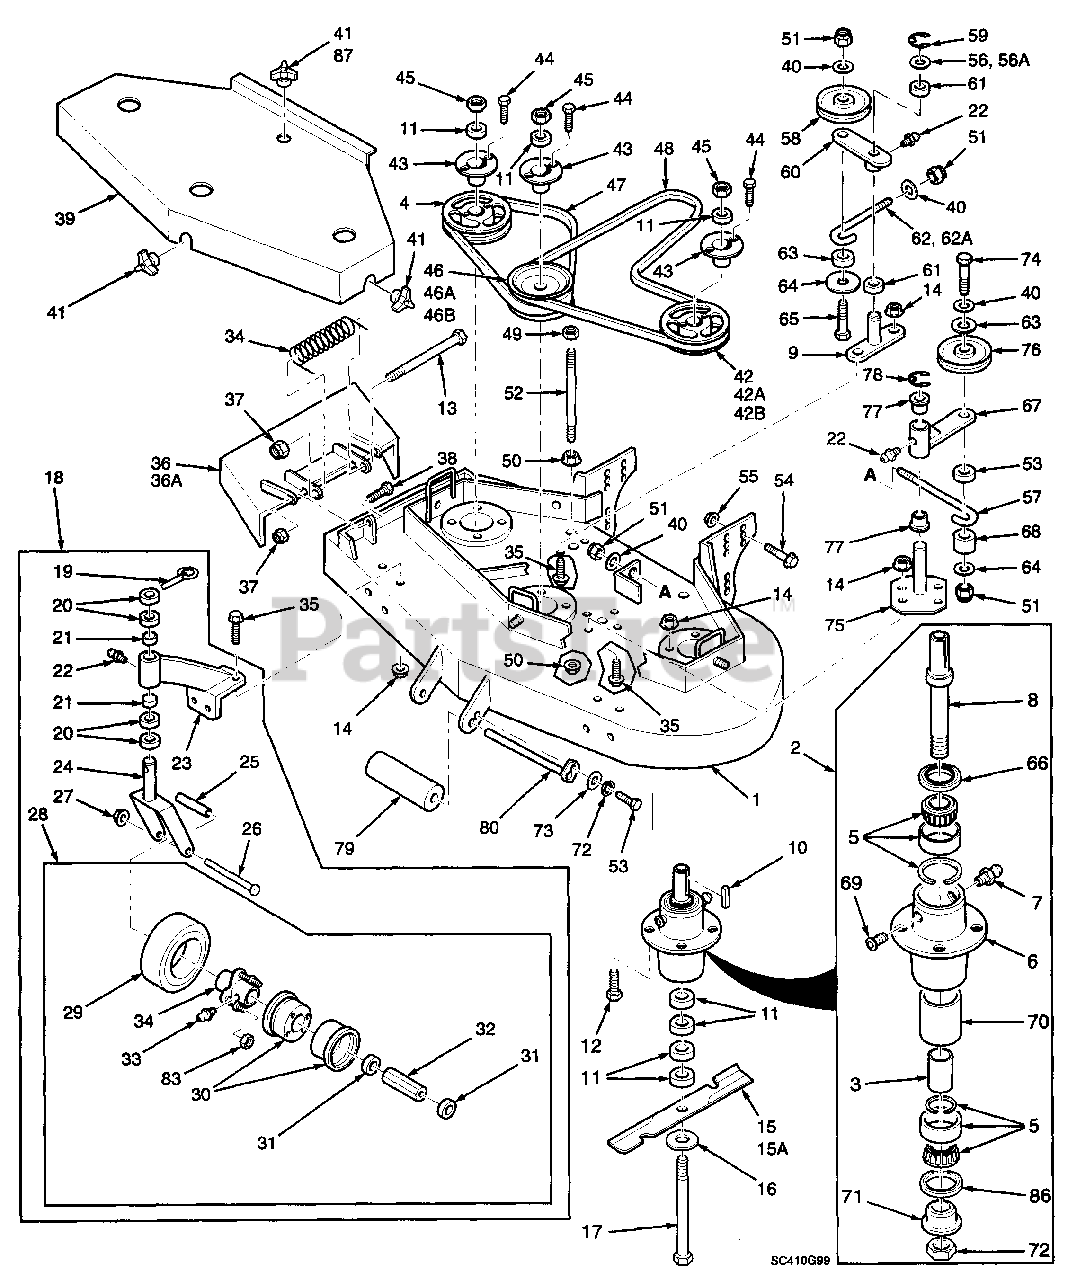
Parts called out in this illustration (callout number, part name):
1	Cutter Deck
2	Spindle Assembly
3	Spacer, Inside
4	Pulley
5	Tapered Bearing (Two)
6	Spindle Housing
7	Grease Fitting Str. 5/16
8	Spindle Shaft, Tapered Brng
9	Idler Pivot
10	Key, 1/4 x 1/4 x 2"
11	Spacer, Cutter Blade - Small
12	Bolt, 5/16-18 x 1-1/4" Hex Head
13	Bolt, 5/16-18 x 4-1/4" Hex Head
14	Serrated Flange Nut, 5/16-18
15	Cutter Blade 16-1/2"
15A	Cutter Blade 16-1/2 Hi Lift
16	Flatwasher, 5/8" (.688 x 1.75 x .134)
17	Hex Head Bolt, 5/8-11 x 9-1/2"
18	Caster Assembly
19	Quick Pin
20	Spacer, Caster Yoke, 1/2" thick
21	Bronze Bearing
22	Lock Wshr, 5/16"
23	Support Assembly
24	Caster Yoke
25	Sleeve, Caster Wheel Bearing
26	Hex Hd Bolt, 1/2-13 x 5-1/2"
27	Elastic Stop Nut, 1/2-13
28	Wheel Assy.
29	Tire only, Caster Wheel
30	Rim Pair, Caster Wheel
31	Bearing Retainer, Caster Wheel
32	Roller Bearing, Caster Wheel
33	Grease Fitting 45 deg., 1/4-28
34	Hub Assembly
35	Capscrew, 5/16-18 x 3/4"
36	Discharge Chute
36A	Discharge Chute
37	Nut, 5/16-18 Elastic Stop
38	Bolt, 5/16-18 x 1" Hex Head
39	Belt Cover
39	Belt Cover 17KA
40	Flat Washer, 3/8" Special
41	Wing Nut, 3/8-16 (Large)
42	Pulley
42A	Pulley
42B	Pulley
43	Tapered Hub
44	Bolt, 1/4-20 x 3/4" Hex Head
45	Nut, 5/8-11 Hex
46	Pulley, Double
46A	Pulley, Double
46B	Pulley, Double
47	Belt, RH Blade Drive
48	Belt, Blade Drive
49	Nut, 3/8-16, Nut Centerlock
50	Nut, 3/8-16, Serrated Flange
51	Nut, 3/8-16 Elastic Stop
52	Support, Belt Cover
53	Bolt, 5/16-18 x 1/2" Hex Head
54	Cpscrw,7/16-14 x 1" Ser Flng H Hd
55	Nut, 7/16-14 Serrated Flange
56	Flat Washer 3/4" Special
56A	Flat Washer 3/4" Special
57	J-Hook
58	Idler Pulley, "V" Groove
59	Retaining Ring, 3/4" Ext."E"
60	Idler Arm Assy.
61	Bronze Bearing
62	J-Rod, Idler Pulley
62A	J-Rod, Idler Pulley
63	Spacer, J-Rod
64	Washer, 3/8 x 1-1/2 x 16 ga.
65	Bolt, 3/8-16 x 2-1/4" Hex Head
66	Seal, Cutter Spindle
67	Idler Arm Assy
68	Spacer, J-Rod
69	Relief Fitting, Cutter Spindle
70	Spacer, Outside, Cutter Spindle
71	Spindle Bushing
72	Nut, Cutter Spindle
74	Bolt, 3/8-16 x 3-1/2" Hex Head
75	Idler Pivot
76	Idler Pulley, Belt Clutch
77	Bronze Bearing
78	Retaining Ring
79	Guide Roller
80	Roller Shaft
83	Nut, 3/8-24 Tapered
86	Seal, Cutter Spindle
87	Wing Nut, 3/8-16 (Small) Top Side
